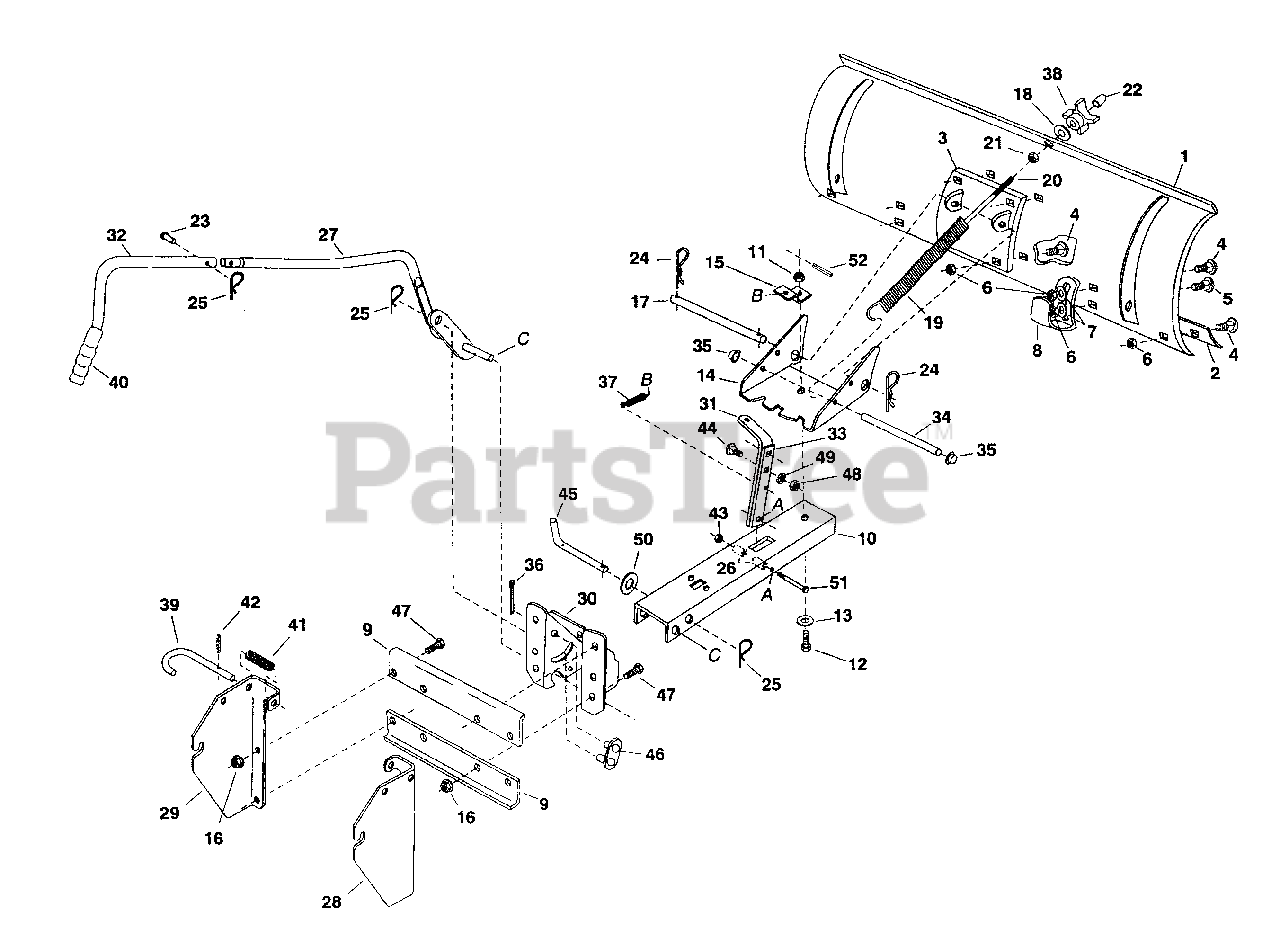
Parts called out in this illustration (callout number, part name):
1	Blade - 46"
2	Wear Plate - 46"
3	Reinforcement Plate Assy.
4	Bolt, Carriage 5/16-18 x 3/4"
5	Bolt, Carriage 5/16-18 x 1"
6	Hex Lock Nut, 5/16-18 Thd.
7	Washer, 5/16"
8	Skid Shoe
9	Bracket, Angle Support
10	Push Channel
11	Hex Lock Nut, 1/2 - 13 Thd.
12	Bolt, Special Pivot
13	Washer, Flat 1/2"
14	Plate, Pivot 7 Ga.
15	Bracket, Spring Mt.
16	Fl. Lock Nut, 3/8-16 Thd.
17	Shaft, Pivot
18	Washer, 3/8" STD.
19	Spring, Blade Adjust
20	Hex Bolt, 3/8-16 x 3-1/2"
21	Hex Nut, 3/8-16 Thd.
22	Plastic Cap
23	Pin, Clevis 1/4" x 1-1/2"
24	Pin, Hair Cotter #4 (1/8")
25	Pin, Hair Cotter #3 (3/32")
26	Spacer, .28 ID x 1"
27	Lift Handle Assembly, Lwr.
28	Hitch Bracket, R.H.
29	Hitch Bracket, L.H.
31	Angle Lock Bar (Long)
32	Lift Handle, Upper
33	Angle Lock Bar (Short)
34	Spring Mount Rod
35	Palnut, 3/8"
36	Cotter Pin 1/8" x 1"
37	Angle Lock Spring
39	Pin, Attachment
40	Handle, Grip
41	Spring, Compression
42	Pin, Spring 3/16" x 1"
43	Hex Lock Nut, 1/4-20 Thd.
44	Carriage Bolt, 3/8-16 x 1-1/4"
45	Channel Pivot Pin
46	Lift Link Assembly
47	Hex Bolt, 3/8-16 x 1"
48	Hex Lock Nut, 3/8-16 Thd.
49	Lock Washer 3/8"
51	Hex Bolt, 1/4-20 x 3-3/4" Lg.Gr 5
52	1/4" x 1" Spring Pin
